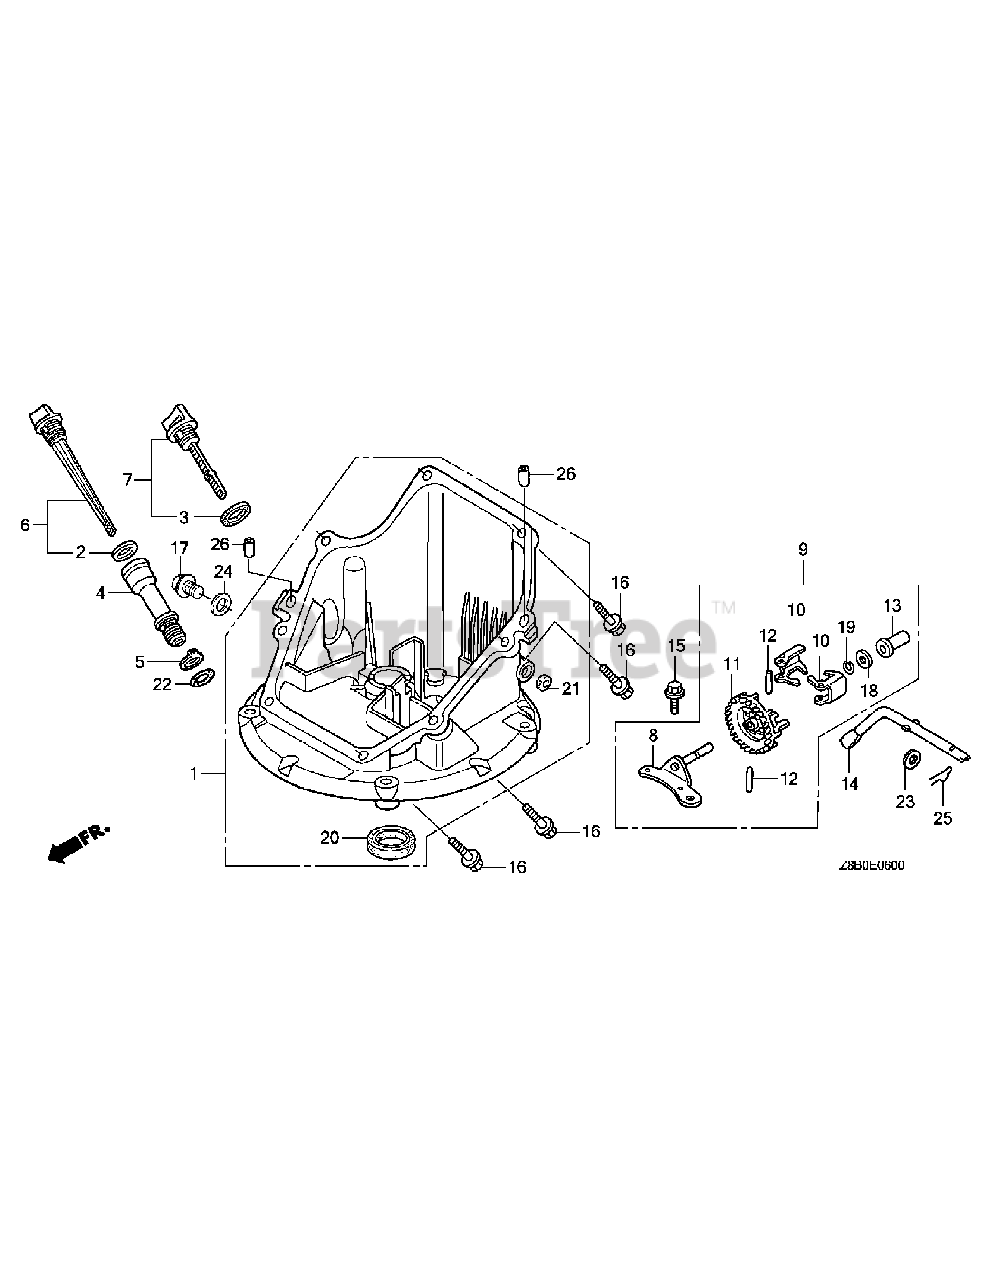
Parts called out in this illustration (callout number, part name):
1	PAN ASSY., OIL (SAE)
3	GASKET, OIL FILLER CAP
7	GAUGE ASSY., OIL LEVEL
8	PRI; SHAFT, GOVERNOR HOLDER
9	PRI; GOVERNOR ASSY.
10	WEIGHT, GOVERNOR
11	HOLDER, GOVERNOR WEIGHT
12	PIN, GOVERNOR WEIGHT
13	SLIDER, GOVERNOR
14	SHAFT, GOVERNOR ARM
15	BOLT, FLANGE (6X14) (CT200)
16	BOLT, FLANGE (6X25) (CT200)
17	SUP; BOLT, DRAIN PLUG (12X15)
17	PRI; BOLT, DRAIN PLUG
18	WASHER, THRUST (6MM)
19	CLIP, GOVERNOR HOLDER
20	OIL SEAL (28X41.25X6)
23	WASHER, PLAIN (6MM)
24	WASHER, DRAIN PLUG (12MM)
25	PIN, LOCK (8MM)
26	PIN, DOWEL (8X20)
